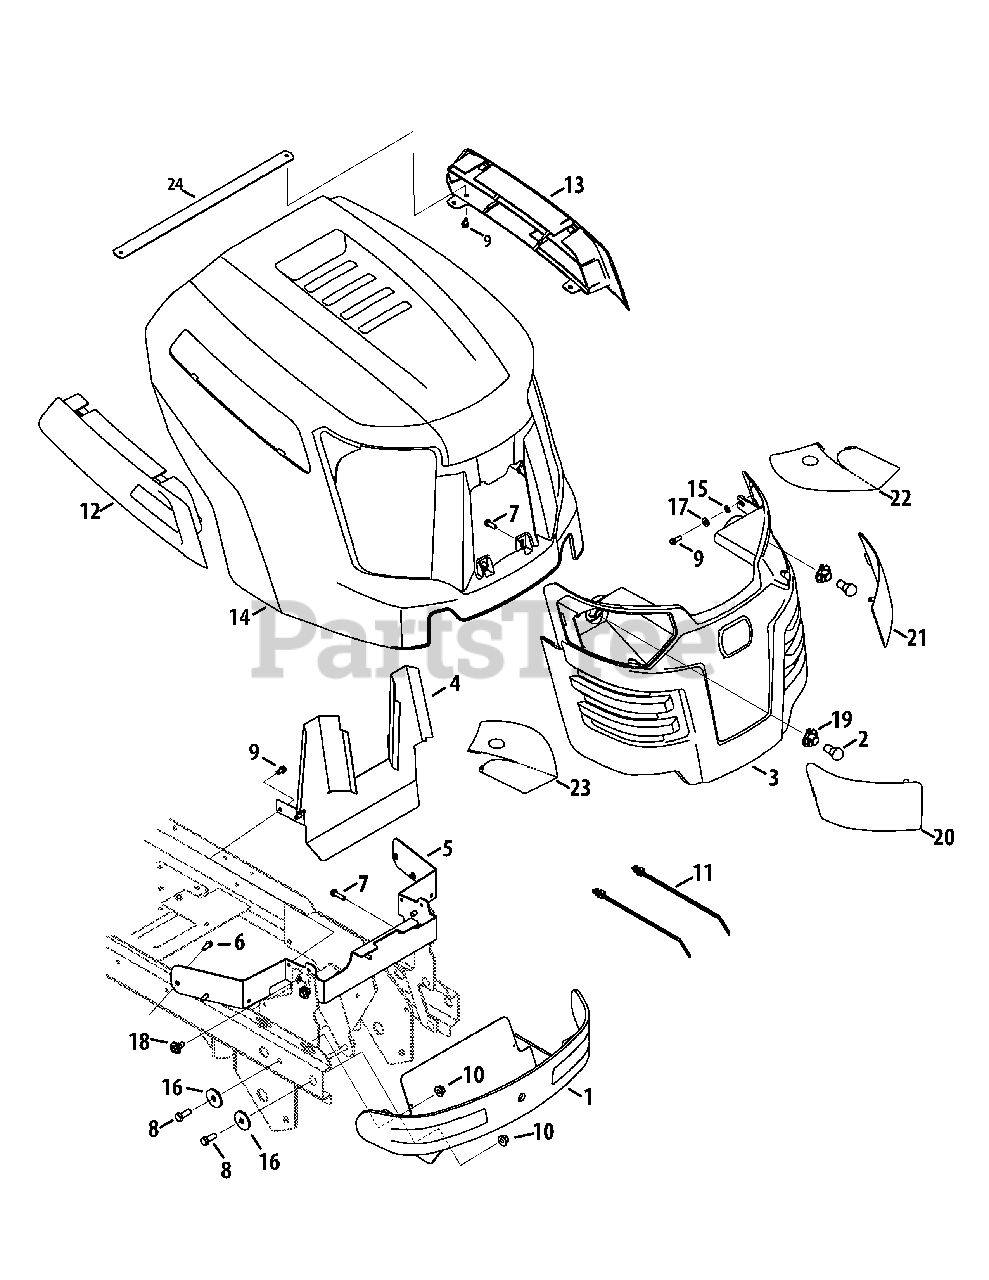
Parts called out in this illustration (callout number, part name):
1	Front Bumper Assembly
4	Heat Shield
5	Hood Pivot Bracket
6	Hex Washer Screw, 1/4 x .750
7	Hex Washer Screw, 5/16-14 x 1.00
8	Hex Screw, 3/8-16 x 1.00
9	Hex Washer Screw, 1/4-20 x 0.500
10	Flange Lock Nut, 3/8-16
11	Cable Tie, 7.5
12	RH Hood Scoop
13	LH Hood Scoop
14	Hood
15	Lock Washer, 1/4
16	Flat Washer, .390 x 1.500 x .134
17	Flat Washer, .271 x .630 x .065
18	Shoulder Screw, 5/16-18 x .43 x .29
19	1/4-turn Socket
20	RH Hood Lens
21	LH Hood Lens
22	Left Lens Reflector Label
23	Right Lens Reflector Label
